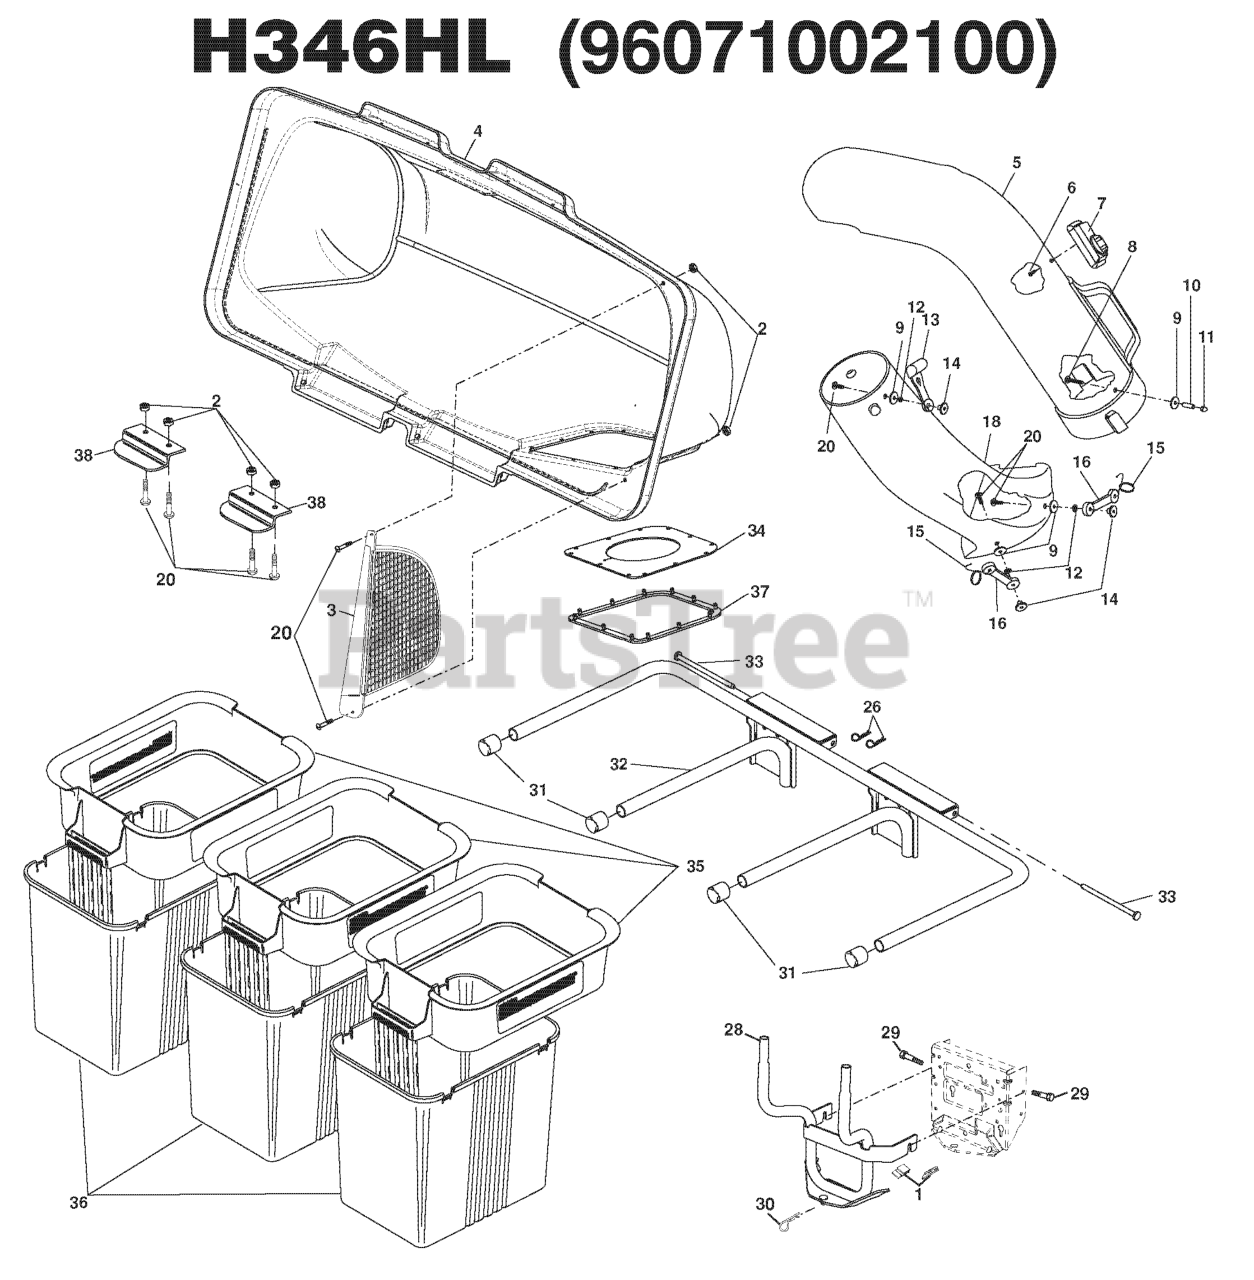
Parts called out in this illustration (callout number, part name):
1	ADAPTER.LT.3-BIN.QA.TEX
3	SCREEN.COVER.BAGGER
4	COVER.ASM.3BIN.GENERIC.
5	CHUTE.UPPER.46"
7	INDICATOR ASM BAG
8	SCREW
11	NUT
12	LOCKWASHER #10
13	LATCH.HOOD.
14	WELDNUT
15	HOOK LATCH
16	RUBBER LATCH
18	CHUTE.LOWER.LT.46"
20	SCREW
26	RETAINER-SPRNG RB
28	BRACKET.BAGGER.3-BIN.BLACK
29	SHOULDER BOLT, SELF-TAP
30	SPRING.RETAINER.YELLOW.ZINC
31	PLUG, TUBING END
32	BAGGER.ASM.FRAME.3BIN.BLACK
33	BAGGER.HINGE.PIN
34	SEAL.BAGGER.TOP.3-BIN.BLK
35	CONTAINER TOP
36	CONTAINER BOTTOM
37	GASKET.COVER.BAGGER
38	LATCH CER38
